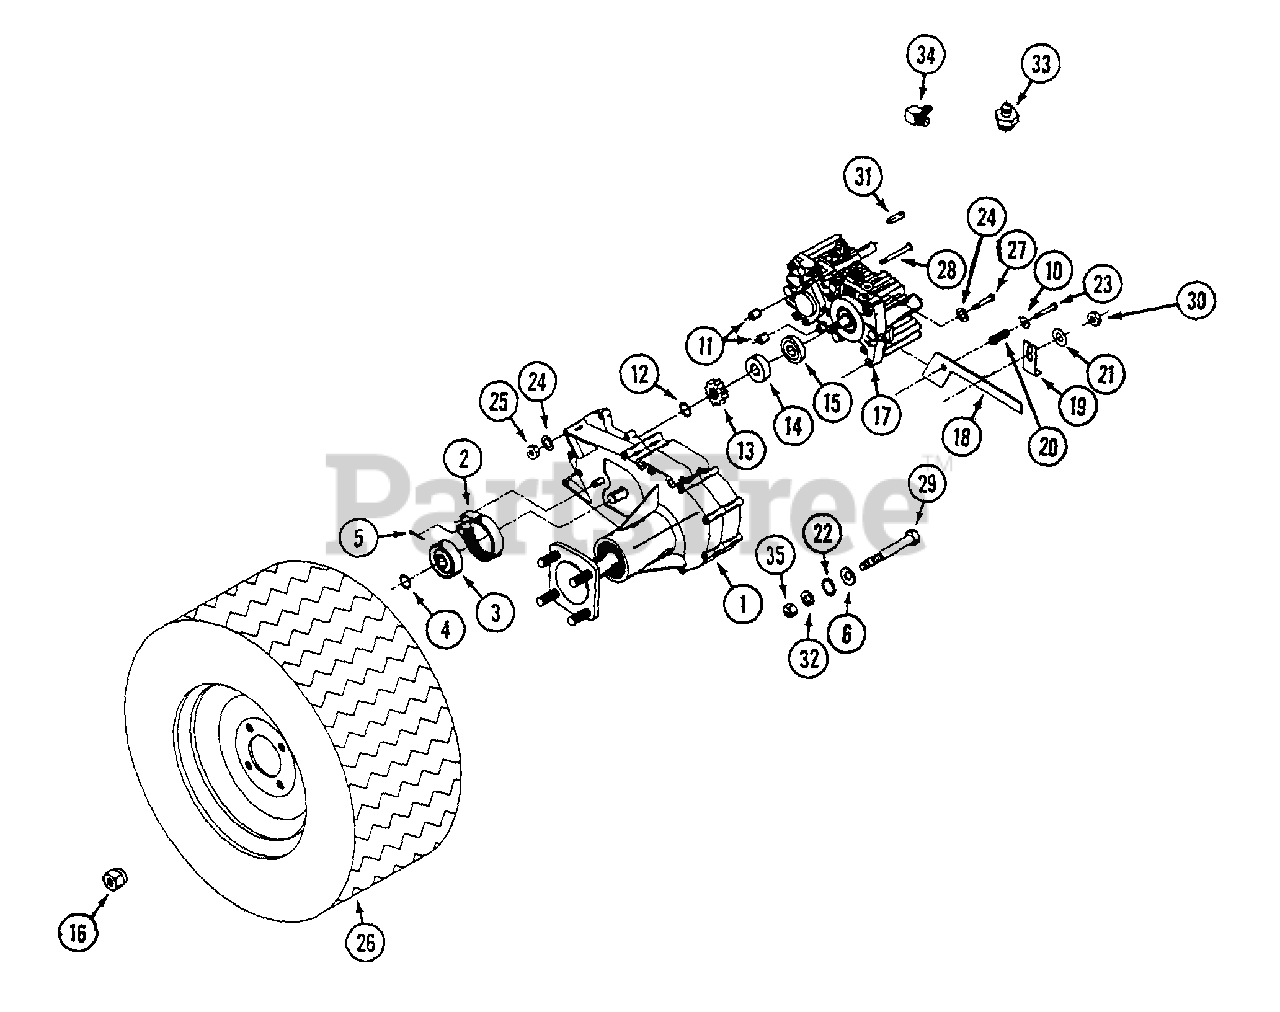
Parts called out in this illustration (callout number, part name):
1	TRANSMISSION - ZT
5	PIN - cotter 3/32" x 3/4"
6	WASHER - .40" x .81"
10	WASHER - 1/4"
12	RING - snap
14	BEARING
16	NUT - lug 1/2" - 20
17	PUMP - hydro R.H.
18	LEVER - transmission dump R.H.
19	BRACKET - dump lever stop
20	SPRING - compression
21	WASHER - 3/8"
22	"O" RING - mounting
23	BOLT - dump lever
24	LOCKWASHER - 5/16"
25	NUT - 5/16" - 18
26	WHEEL ASSEMBLY
27	BOLT - 5/16" - 18 x 1-3/4"
28	BOLT - 5/16" - 18 x 7-1/2"
29	BOLT - 3/8: - 16 x 3-1/2
29	BOLT - 3/8" - 16 x 4" mounting
30	NUT - 3/8" - 16 lock
31	KEY - 5 x 5 x 25 mm
32	LOCKWASHER - 3/8"
33	ADAPTER - pump outlet
34	ADAPTER - 90° pump inlet
35	NUT - 3/8" - 16
